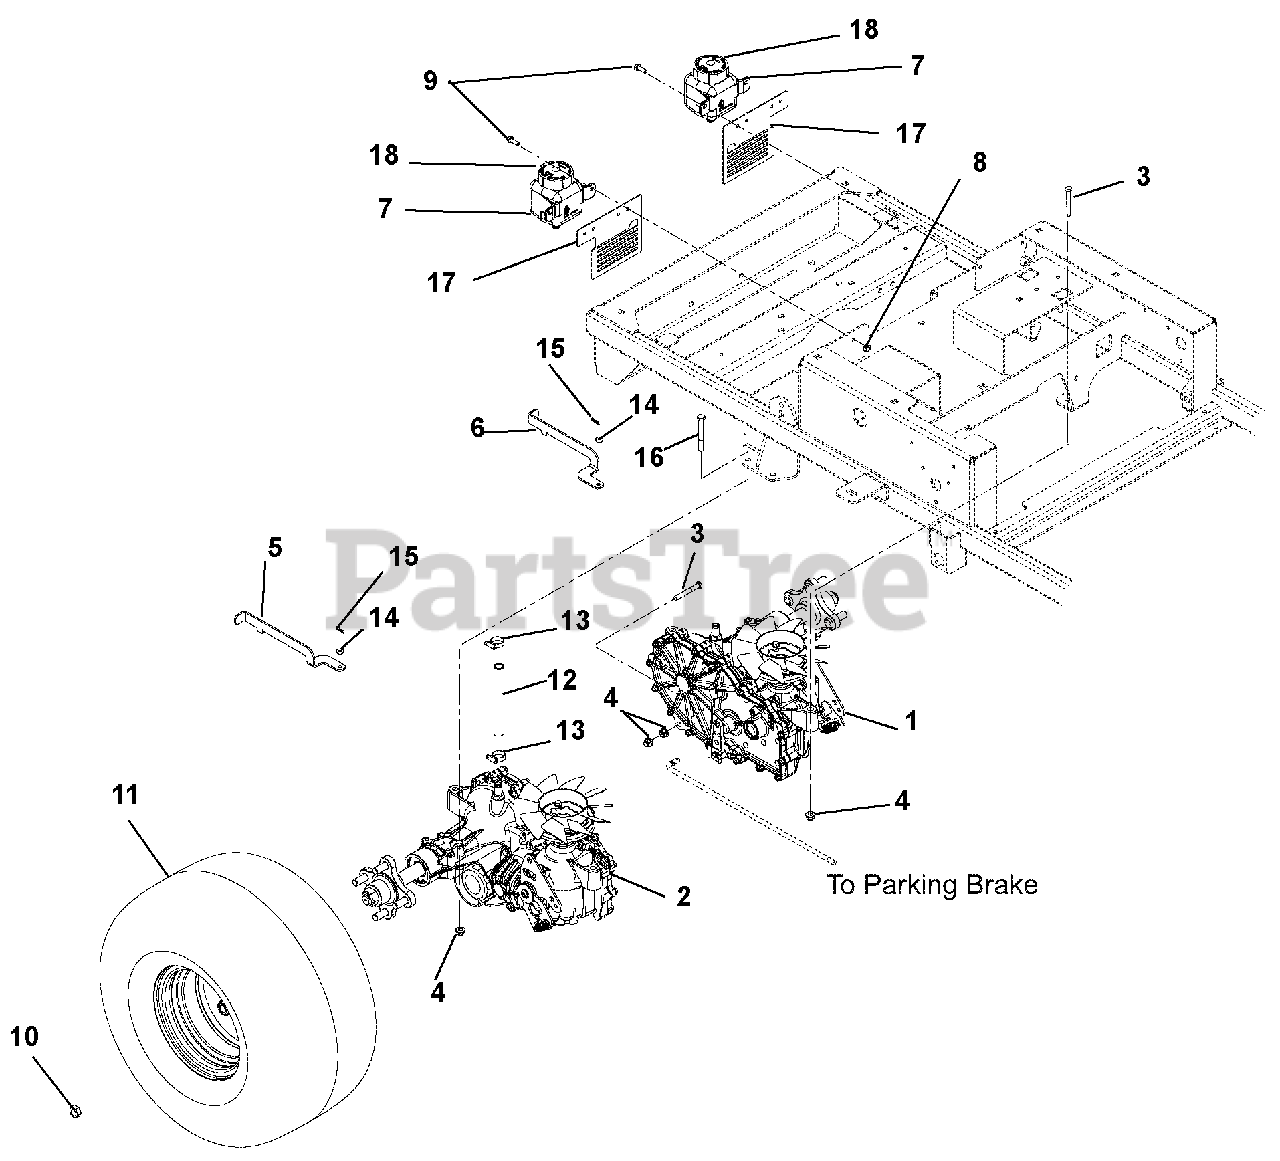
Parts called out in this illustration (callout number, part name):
1	TRANSAXLE, ZT2800 LH
2	TRANSAXLE, ZT2800 RH
3	@BLT-HEX .31-18X2.25 GR5 YWZC
4	@NUT-LK-NYL-FLG .31-18 YWZC
5	DUMP VALVE, RH
6	DUMP VALVE, LH
7	TANK, EXPANSION
8	@NUT-LK-TOP-FLG .25-20 YWZC
9	@BLT-HEX .25-20X.75 GR5 YWZC
10	WHEEL NUT .500-20 YZ
11	TIRE/WHEEL ASM, 20X8.0-8 (SQ)
12	HOSE, OIL RESERVOIR
13	CLAMP,.88 DIA. HOSE
14	WSHR-FL-STL .265X.50X.087YWZC
15	PIN-HAIR INT .06X.18X.77
16	@BLT-HEX .31-18X2.75 GR5 YWZC
17	BRKT, REAR FAN GUARD
18	CAP, HYDRO RESERVOIR REPLAC.
